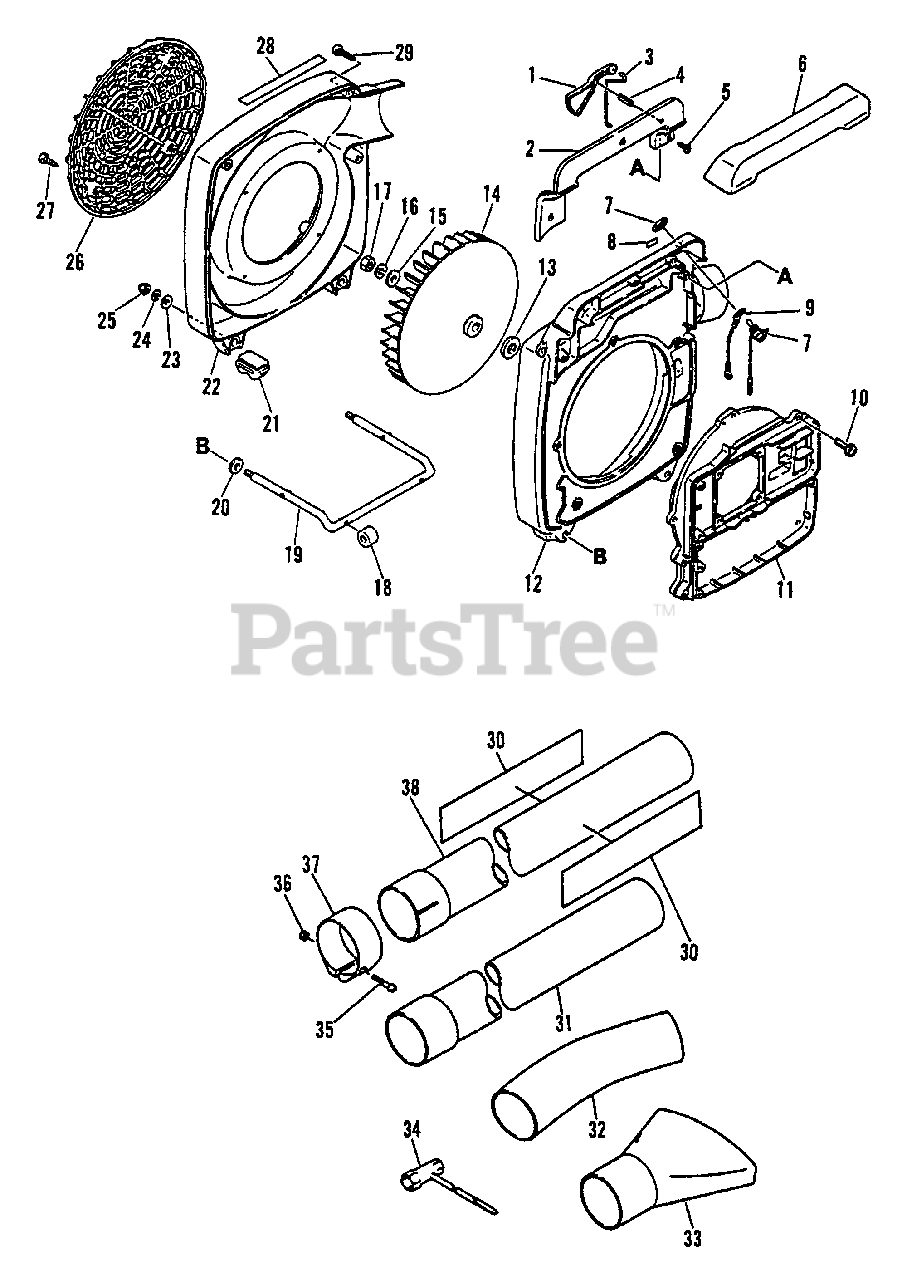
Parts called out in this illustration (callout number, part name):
1	TRIGGER, THROTTLE
2	COVER, HANDLE
3	ROD, THROTTLE
4	PIN - SPRING -- 5X18
5	SCREW - 4X16
6	GRIP, HANDLE
7	IGNITION SWITCH ASSY
8	LABEL - STOP
9	LEAD - GROUND
10	SCREW - 5X20
11	BRACKET, ENGINE
12	COVER, FAN - RIGHT
13	WASHER - 10
15	WASHER - 8
16	LOCKWASHER - 8
22	COVER, FAN - LEFT
23	WASHER - 6
24	LOCKWASHER - 6
25	NUT - 6 -- CAP
26	GUARD, DEBRIS
27	SCREW - 5X20
28	LABEL - MODEL
29	SCREW - 5X25
30	LABEL - ECHO
31	TUBE, BLOWER - STRAIGHT
32	TUBE, BLOWER - CURVED
33	NOZZLE - FAN HEAD
34	T-WRENCH - 13X19mm
35	SCREW - 4X25
37	CLAMP KIT
38	BLOWER TUBE KIT - STRAIGHT
